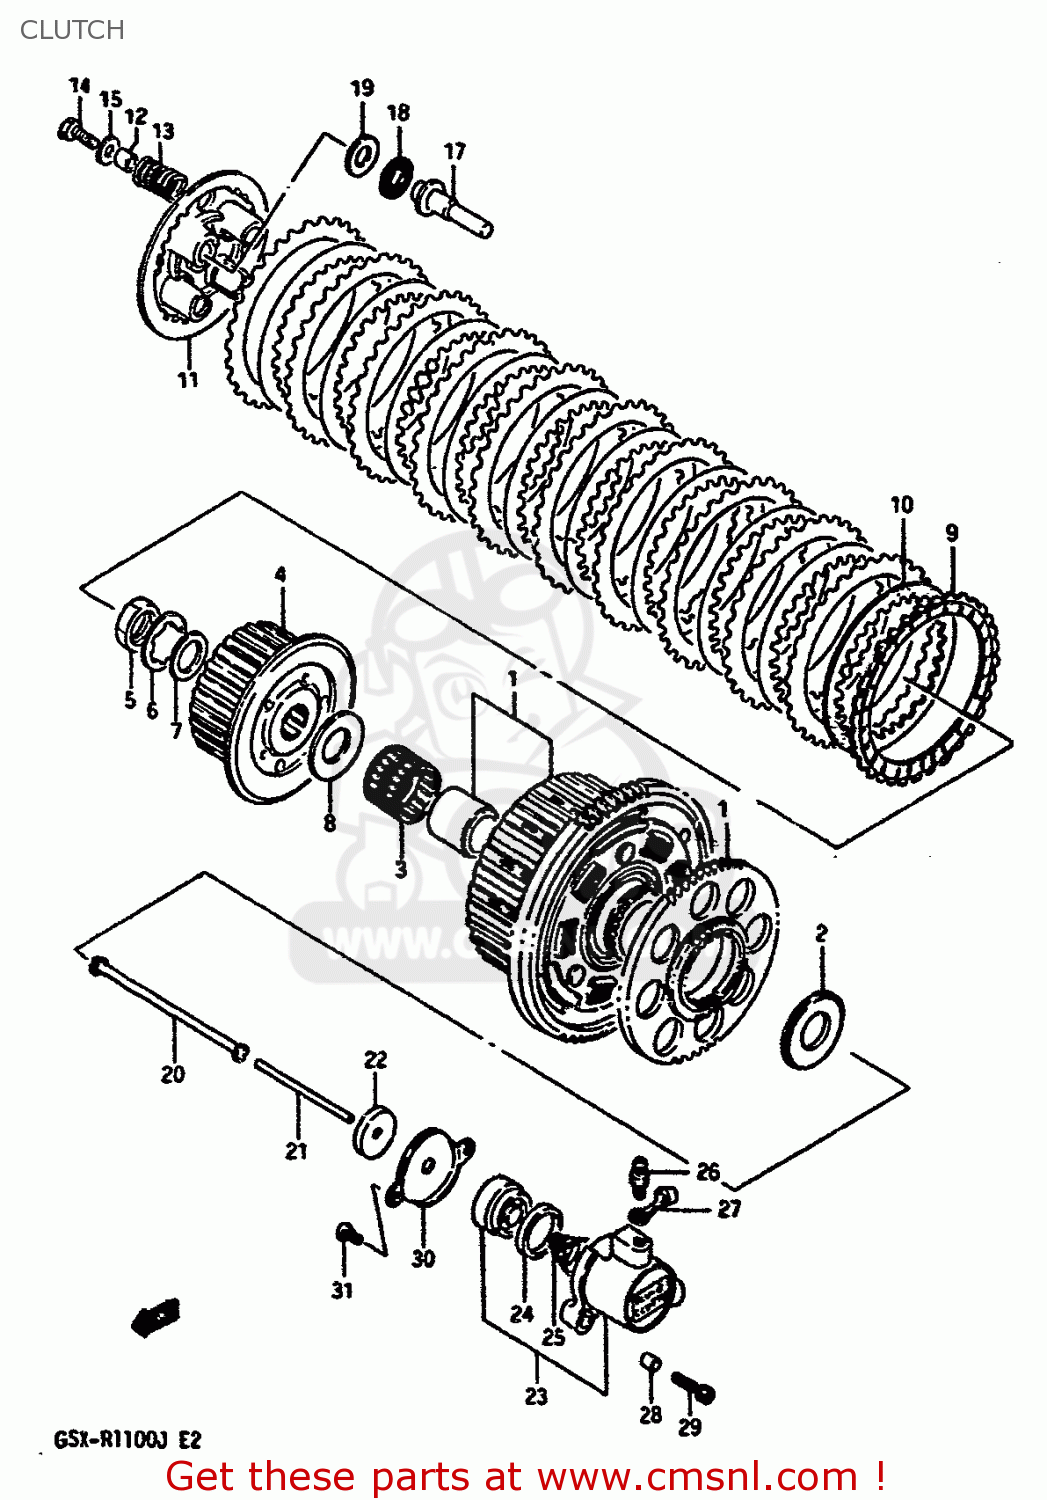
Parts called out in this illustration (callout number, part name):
1	GEAR ASSEMBLY,PRIMARY DRIVE
2	WASHER
3	BEARING(35X40X35.8)
4	HUB,CLUTCH SLEEVE
5	NUT
6	WASHER,LOCK
7	WASHER
8	WASHER(25X50X2.5)
9	PLATE,CLUTCH DRIVE (MCA)
10	PLATE,CLUTCH DRIVEN (NAS)
11	DISC,CLUTCH PRESSURE
12	SPACER(6.2X12X14)
13	SPRING
14	BOLT 6X30
15	WASHER
16	GEAR,GENERATOR DRIVE
17	PIECE,CLUTCH PUSH
18	BEARING(15X28X2)
19	WASHER
20	ROD,CLUTCH
21	ROD,CLUTCH PUSH,L
22	SEAL,OIL(6X34X5.5)
23	CYLINDER,CLUTCH RELEASE
24	CUP
25	SPRING,CLUTCH CYLINDER
26	BLEEDER
27	CAP,BLEEDER
28	PIN
29	BOLT
30	PLATE,CLUTCH PUSH ROD
31	SCREW
